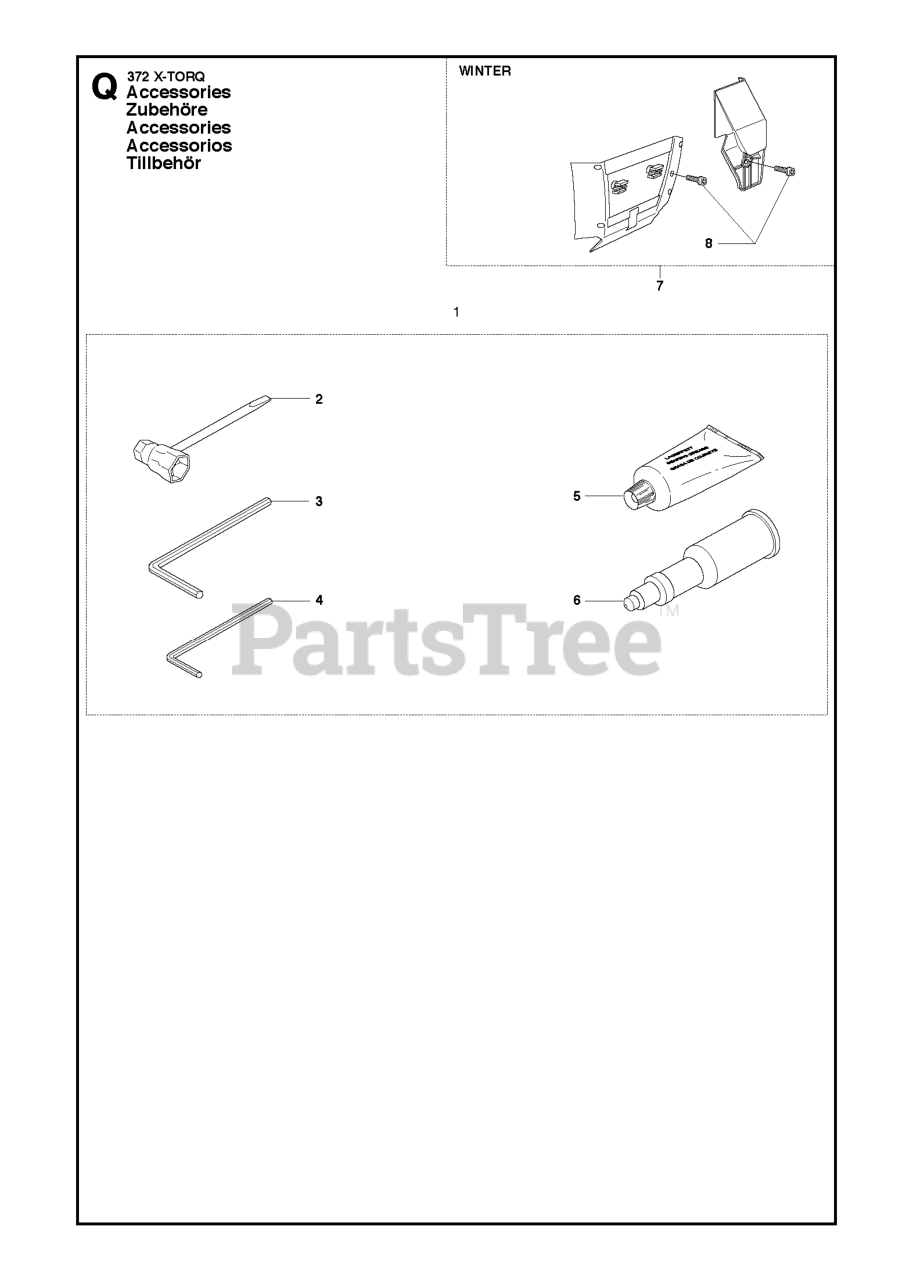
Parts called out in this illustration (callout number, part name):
1	TOOL KIT
2	COMBI TOOL
3	L-SPANNER
4	L-SPANNER
5	GREASE
6	Grease Gun
7	WINTER KIT
